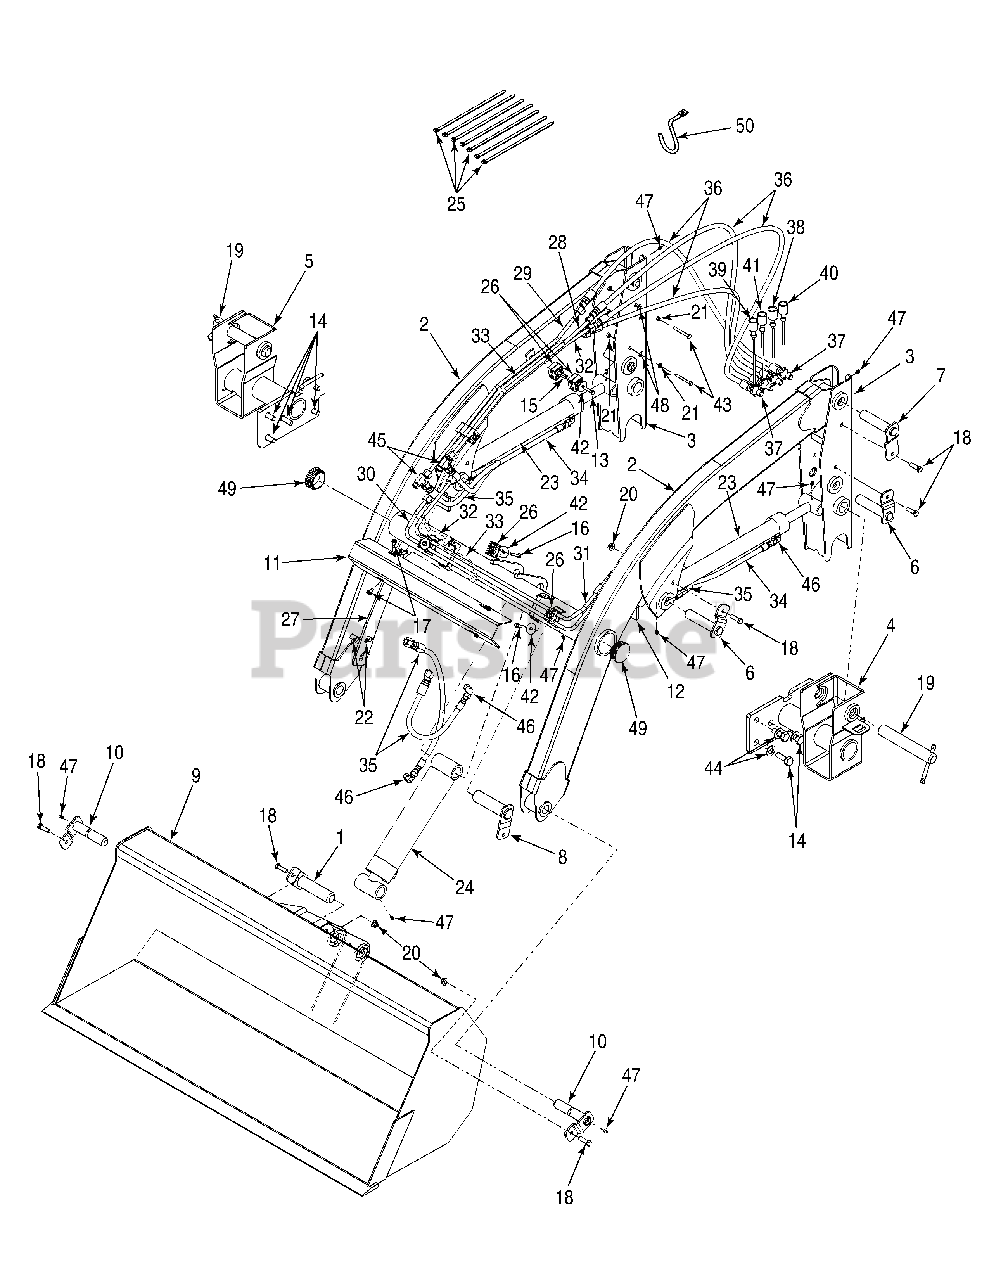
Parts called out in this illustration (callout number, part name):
2	Boom Assembly
3	Mast, Vertical Support LH
7	Pin, Loader - Long
8	Pin, Bucket Cylinder
9	Bucket, Loader
11	Bracket, Tube Cover
12	Stand, Loader - LH
13	Screw, Hex Cap, 1/4-20 x 1.25 Gr5
14	Screw, Hex Cap, M16-2.4 Gr8.8
15	Bolt, Stacking, 1/4-20 x 3/4
16	Screw, Hex Tapp, 1/4-20 x 1.5
17	Screw, Hex Wash. Hd. Tapp 1/4-20 x .625
18	Screw, Hex Cap, 3/8-16 x 1.25 Gr5
19	Pin, Mast Mounting
20	Nut, Hex Flange Insert Lock 3/8-16 GrF
21	Nut, Hex, 1/4-20 Gr5
22	Pin, Internal Cotter
23	Cylinder, Boom Lift
24	Cylinder, Loader Bucket
25	Tie, Cable - Tie hose to cylinders
26	Clamp, Tube
27	Stand, Loader - RH
28	Tube, Hydraulic - Boom Raise
29	Tube, Hydraulic - Boom Lower
30	Tube, Hyd., U Shape - Boom Lower
31	Tube, Hyd., U Shape - Boom Raise
32	Tube, Hydraulic - Bucket Dump
33	Tube, Hydraulic - Bucket Curl
34	Hose, Hydraulic, 26 inch
35	Hose, Hydraulic, 19 inch
36	Hose, Hydraulic, 60 inch
37	Coupling, Mail Quick Connect
38	Cap, Coupler Protective - Green
39	Cap, Coupler Protective - Yellow
40	Cap, Coupler Protective - Blue
41	Cap, Coupler Protective - Red
42	Washer, Flat, .285 x 1.25 x .06
43	Screw, Hex Cap, 1/4-20 x 2.25 Gr5
44	Washer, Flat, .69 x 1.25 x .075
45	Fitting, Branch Tee, 3/8
46	Fitting, Elbow, 1/4 x 1/4 Orb
47	Fitting, Lube
48	Washer, Flat, .25 x .63 x .0515
49	Plug, Tube End
